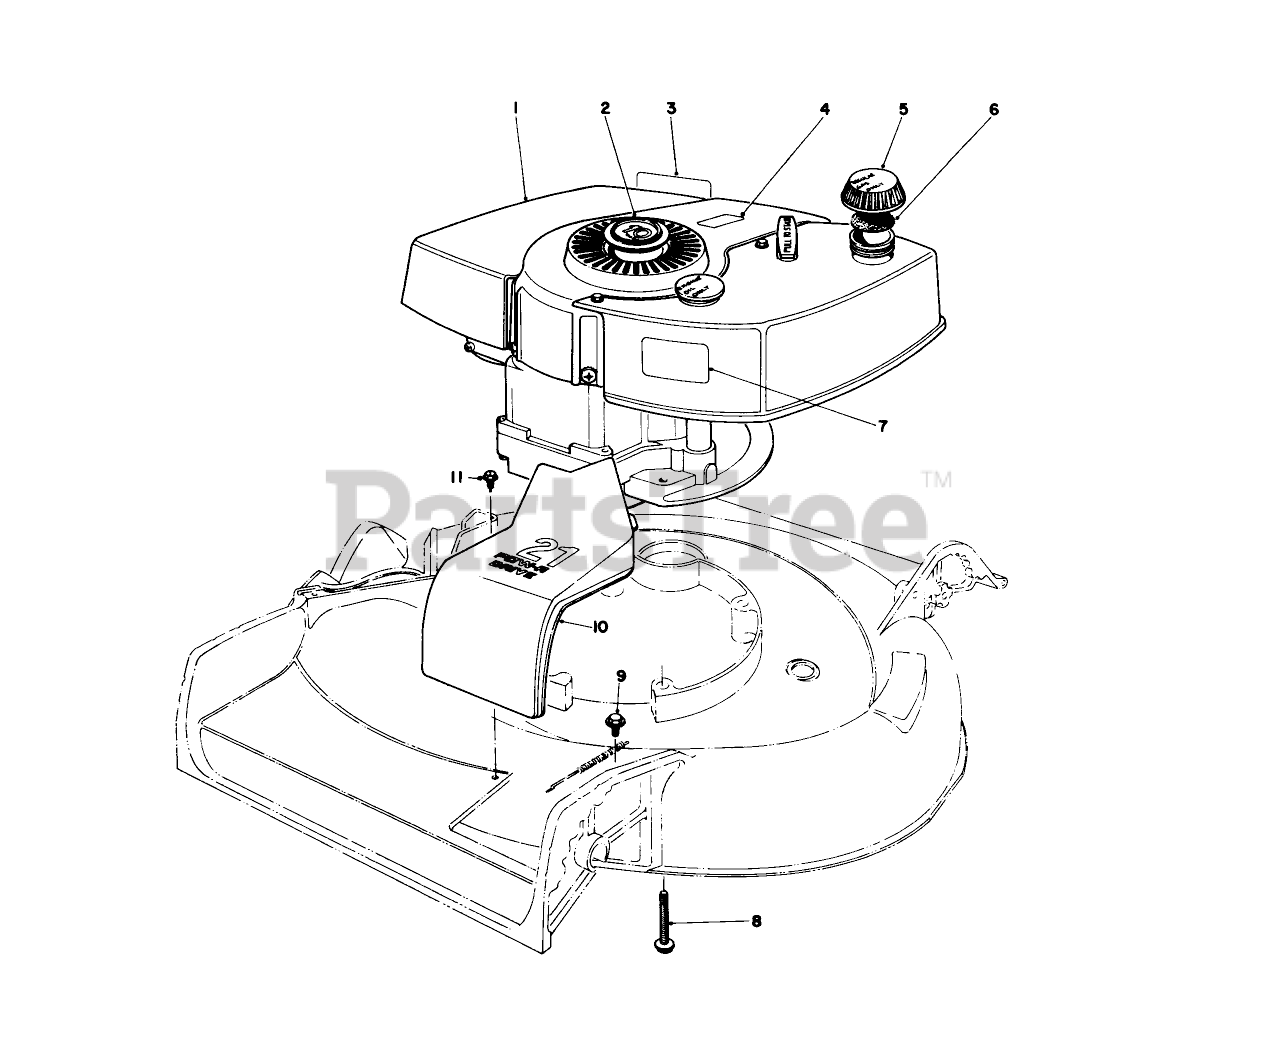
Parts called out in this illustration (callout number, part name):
1	Engine
2	PLUG BUTTON
3	Decal Maintenance
4	Decal-Caution
5	Gas Cap Assembly (Incl. Ref. #6)
6	GAS CAP GASKET
7	Decal
8	3/8-16 X 2-3/4 CAPSCR
9	SCREW-HWHTF
10	Cover Belt Drive
11	SCREW-HWHTF
